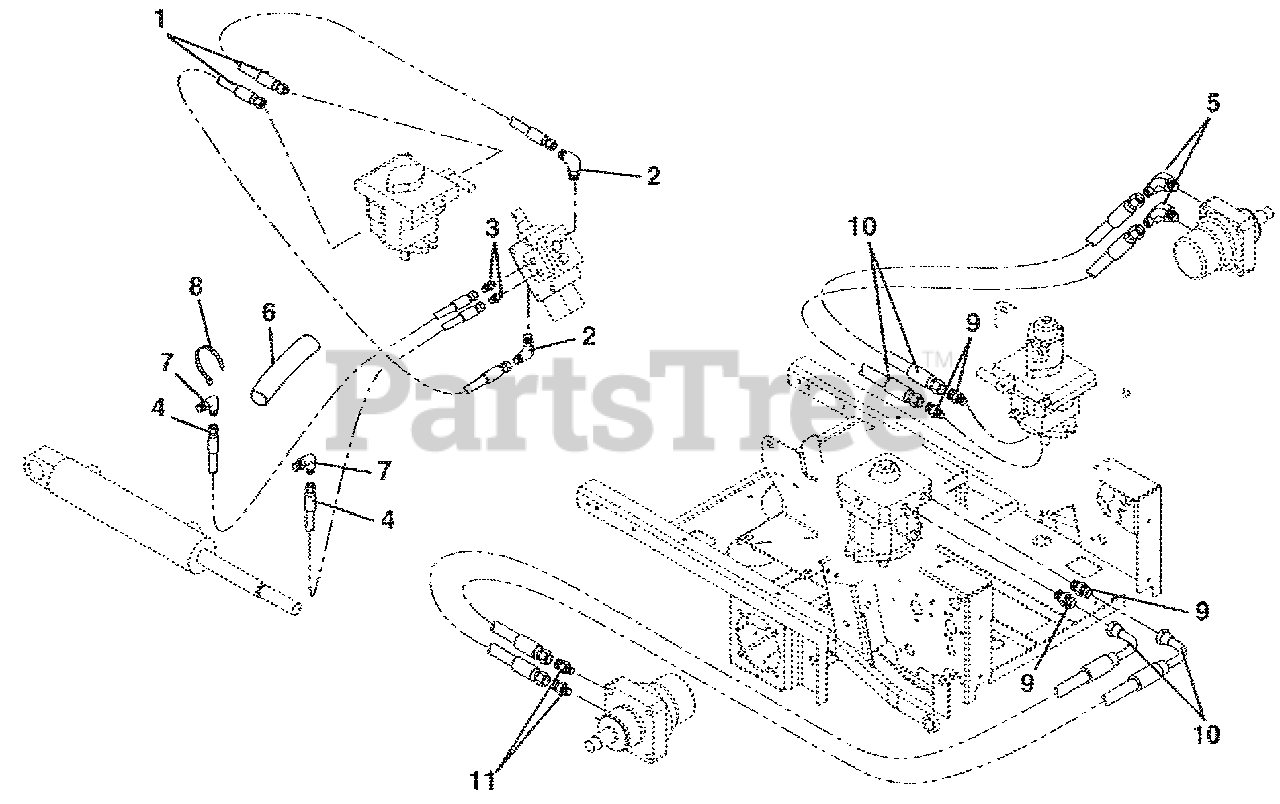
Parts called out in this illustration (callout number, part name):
1	Hose, Hydraulic
2	Hydraulic, Fitting Elbow
4	Hose, Hydraulic
5	Fitting, Hydraulic
6	Sleeve, Protective 24 in.
7	Fitting, Hydraulic
8	Cable Tie
9	Adapter, Face Seal 8 x 8 .50 O-Ring
10	Hose, Hydraulic .50
11	Adapter, Hydraulic Steel .875 to .75
